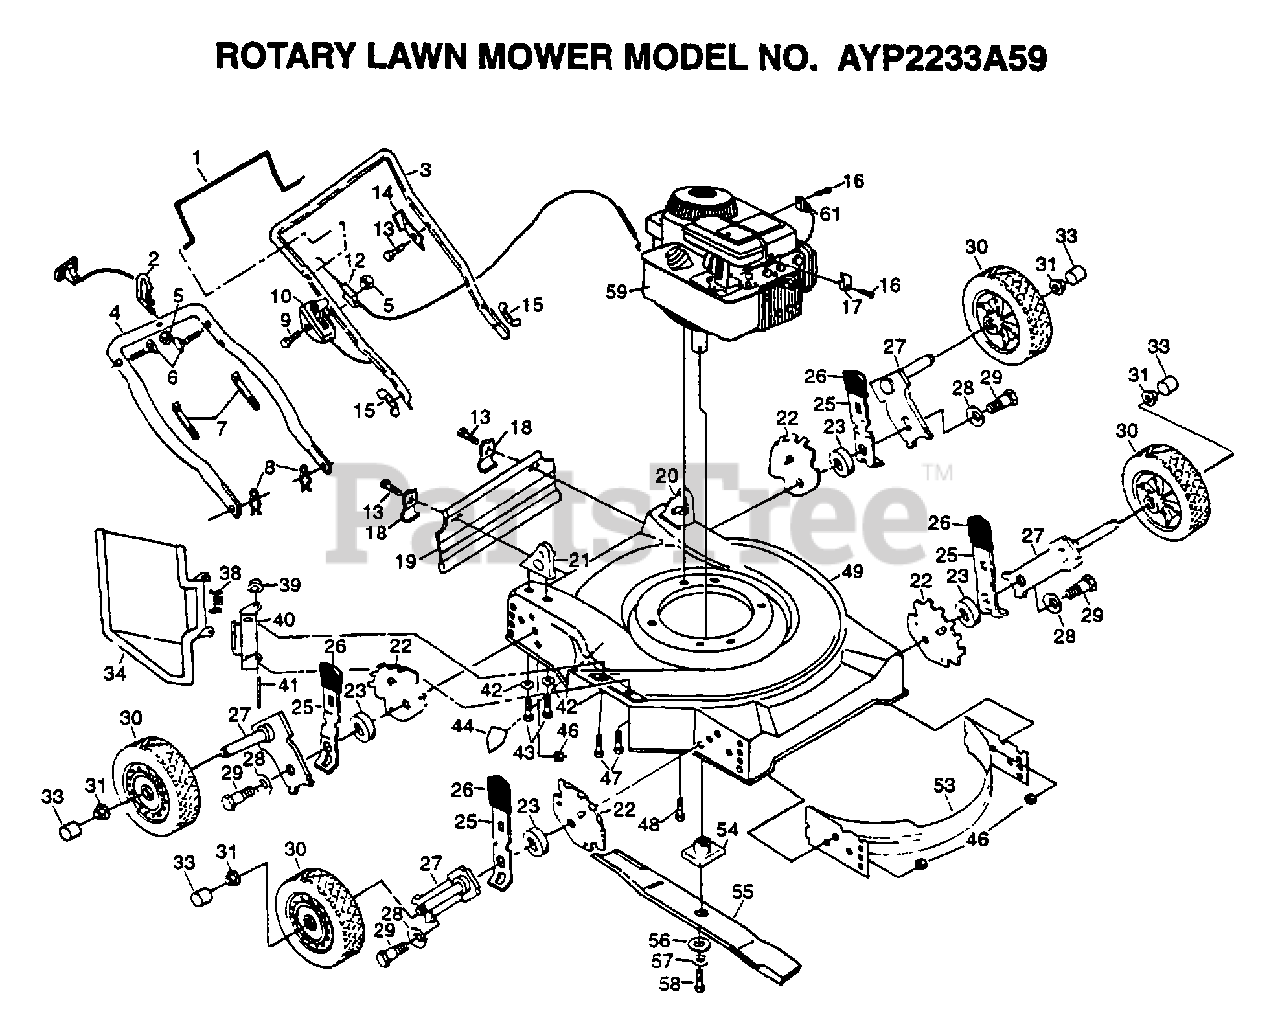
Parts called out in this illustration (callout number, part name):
1	CONTROL BAR PM
2	ROPER GUIDE PM
6	BOLT.HANDLE.LM
8	HAIRPIN COTTER
9	SCREW.HXHD.WASH.
10	CONTROL THROTTLE
12	"CABLE,ENG ZONE CO"
13	TAPPING SCREW
14	"BRKT,UPSTOP"
15	"NUT,WING PM"
16	SCREW PM
17	CABLE CLAMP
18	"BRKT,DEFL PM"
19	SKIRT.REAR.FGD.22
22	BRACKET.WHL.ADJ.9
25	SPRING SELECTOR
26	KNOB PM
27	AXLE ARM
28	"WASHER, BELLEVIL."
30	WHEEL.ASM
31	HEX FLANGE LOCKNT
33	HUB CAP-PLASTIC
38	"SPRING,TORSION"
39	PUSH ON SPEED NUT
40	"BRKT,HSG"
41	"ROD,HINGE "
42	STEEL WASHER
43	SCREW
44	DECAL-DANGER PM
46	LOCKNUT PM
47	SCREW
48	SCREW
49	KIT.HSG.22SD.PUSH
53	BAFFLE.FRT/REAR
54	BLADE ADAPTOR
55	"BLADE.MULCH.22"""
56	"WASHER,HARDEN"
57	LOCKWASHER
58	SCREW
61	GUIDE CLIP PM
